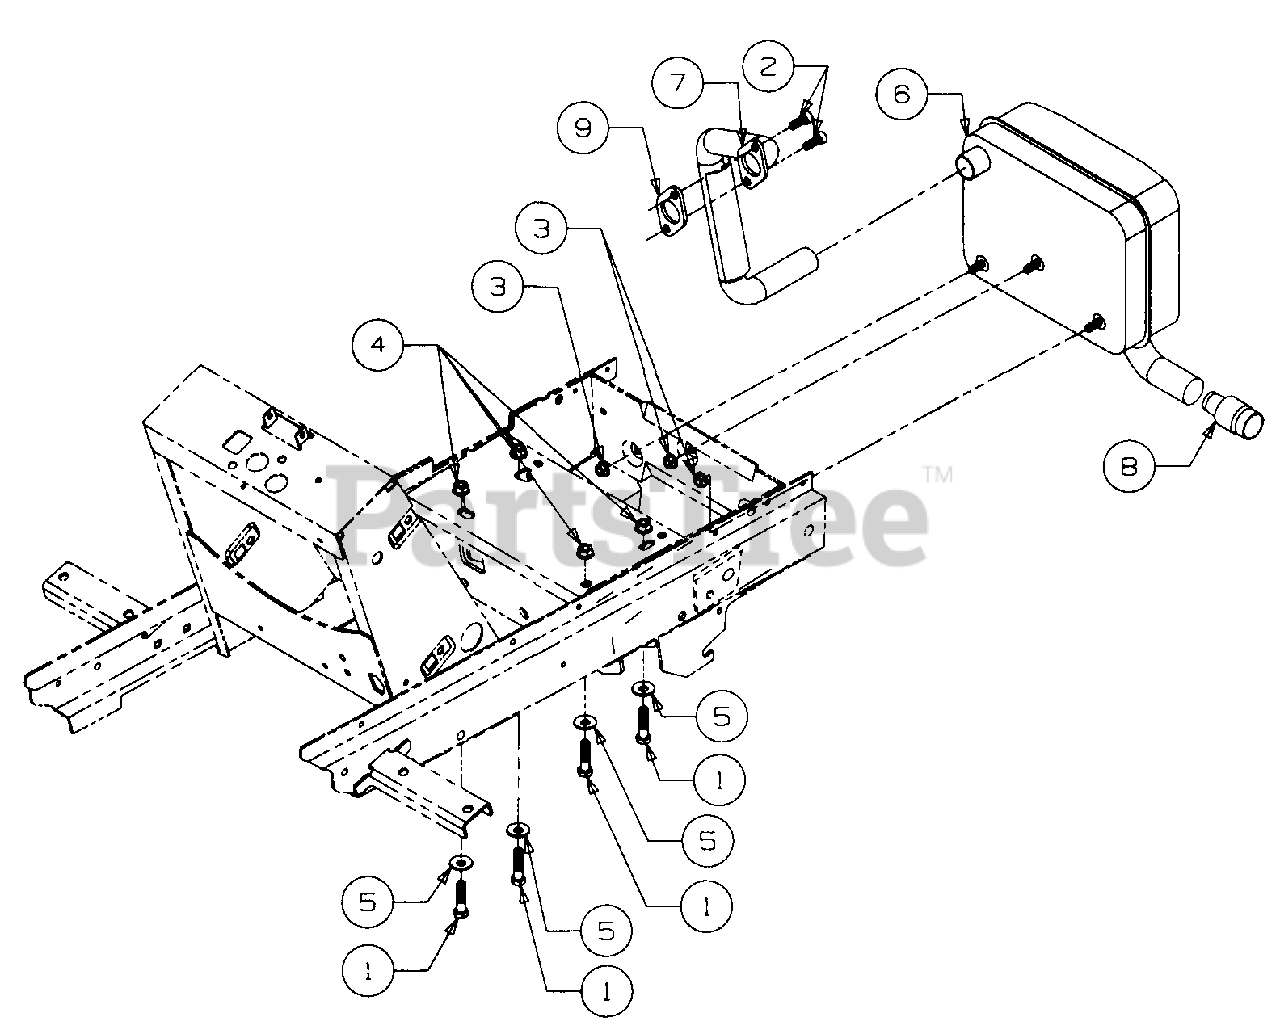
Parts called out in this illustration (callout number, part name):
1	Bolt, Engine Mtg, 3/8-24 x 1.75 Lg GR5
2	Screw, Socket Hd Cap, M8-1.25 x 20 mm Lg
3	Nut, Hex Flange Top Lock, 5/16-18
4	Nut, Hex Flanged Lock, 3/8-24
5	Washer, Bell, .380 x .88 x .062 Thk
6	Muffler Assembly
7	Tube,Exhaust
8	Arrestor, Spark
9	Gasket, Exhaust
